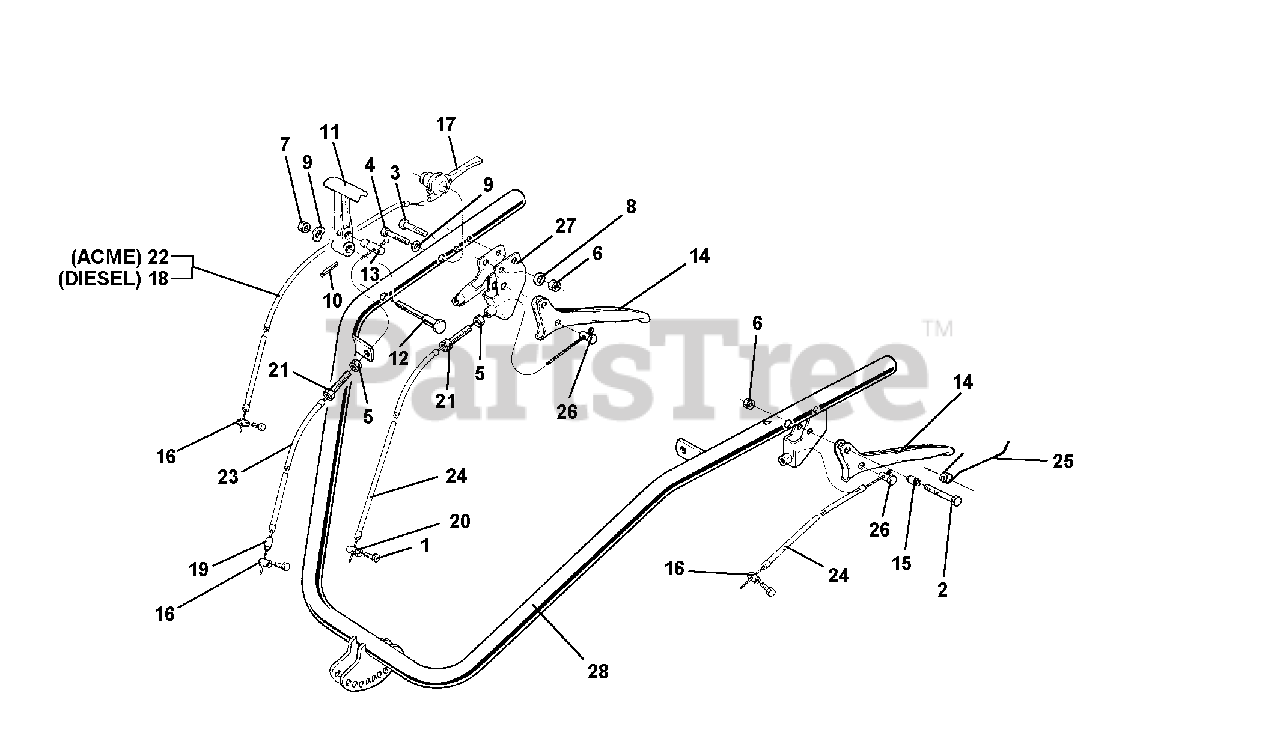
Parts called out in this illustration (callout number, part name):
1	SCREW TE M6 X 14
2	SCREW M6 X 25
3	SCREW M6 X 40
4	SCREW TE M8 X 40
6	NUT, SELF LOCKING M6
7	NUT, SELF LOCKING M8
8	WASHER, LOCK 6.4
9	WASHER, LOCK 8.4
10	PIN, LOCKING 4 X 20
11	LEVER DIFFERENTIAL LOCKING
13	DRILLED PIN
15	LEVER SPACER
16	CLAMP, CABLE
17	LEVER, ACCELERATOR
18	CABLE & SHEATH, ACCEL AD114
19	END, SHEATH
20	PIN, CABLE CLAMP
21	SCREW, ADJUSTING M8
22	CABLE & SHEATH, ACCEL. L 1380
23	WIRE AND SHEATH L 800
24	SHEATH CABLE
25	LEVER SPRING
27	COUPLING FOR DOUBLE LEVER
